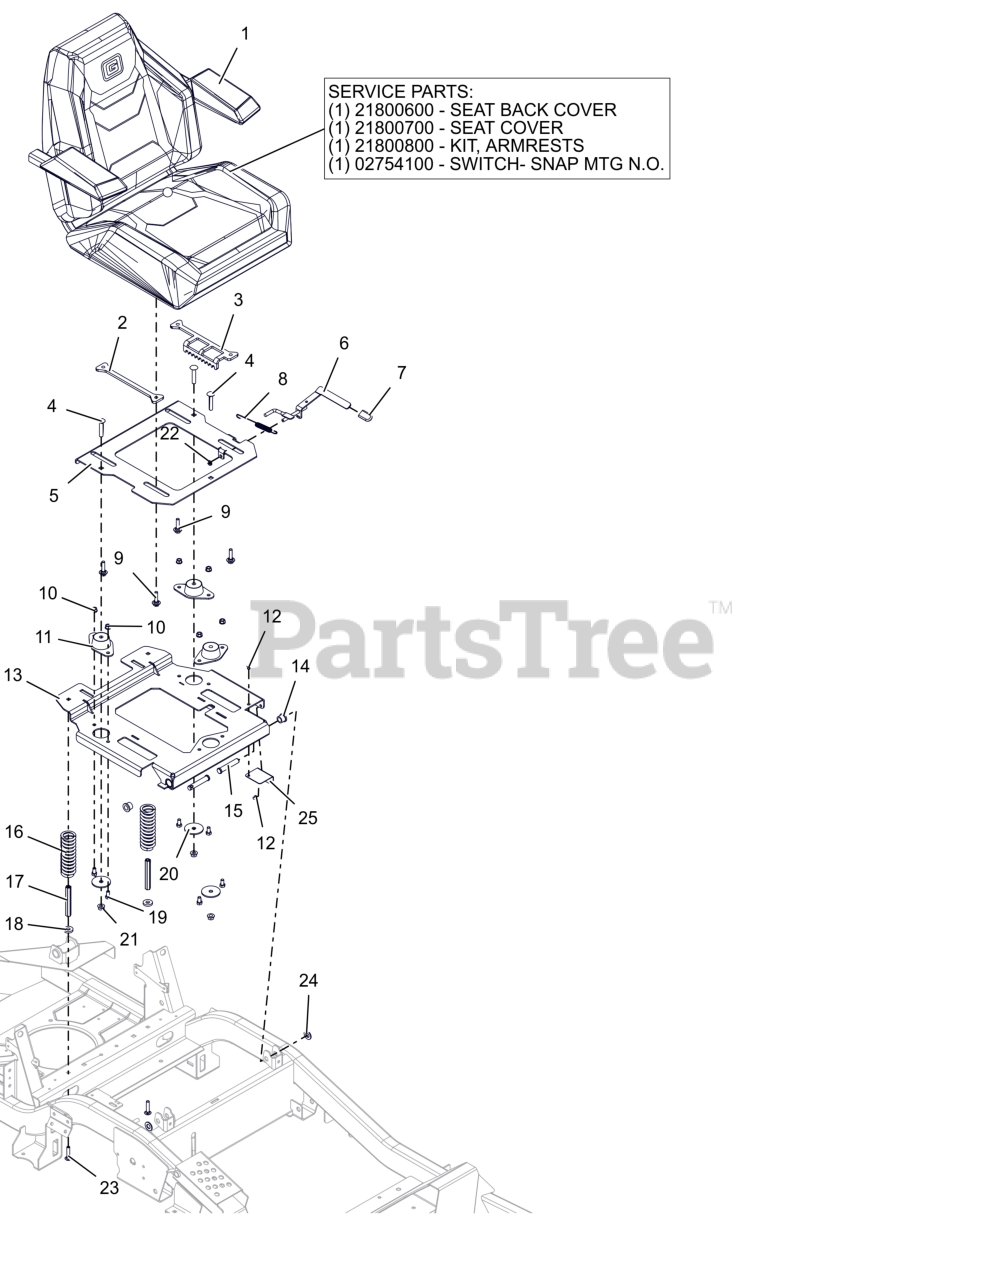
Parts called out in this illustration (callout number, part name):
1	SEAT- ZTXL MY23 (WOOD)
1	KIT- ZTXL CUSTOM BACK COVER
1	KIT- ZTXL CUSTOM SEAT COVER
1	KIT- ARMRESTS (CUSTOM PAD)
1	SWITCH- SNAP MTG N.O.
2	PLATE, ADJ SEAT SLIDE (BLACK)
3	PLATE, SEAT ADJ (BLACK)
4	BLT,RHSSN.375-16X2.00 G5 ZCC
5	PLATE- SEAT MTG 3PT (ISO KIT)
6	WLDMT, SEAT SLIDE LEVER
7	GRIP, SEAT LEVER, GREY
8	SG-TENS .06X.482X5.35
9	BLT, SHLDR .31-18 X .175
10	NUT,LK-CTR-FLG .31-18 GF ZCC
11	MOUNT- FAIL-SAFE COMPRESSION
12	RIVET, .1875 AL/AL .126-.250
13	WLDMT- ISO MTG PLATE 3PT
14	BSHG, FLG .516X.750X.625X.937
15	PIN, SLIC-.500X42.70X2.31 -ZC
16	SPRING, COMPRESSION SEAT 224LB
17	NUT, COUPLING 5/16X18 X 3.75
18	WSHR, FLT .406X1.00X.188 ZCC
19	BLT, HEX .31-18X.625 G5 ZCC
20	WSHR-FL-STL 0.406X2X0.125 ZCC
21	NUT-LK-CTR-FLG .375-16 GF ZCC
22	NUT-PUSH .312
23	BLT,RHSN .31-18X1.50 G5 ZCC
24	WSHR-FL-NYL .518X1.000X.080
25	GUARD, SEAT FAN (SH)(BLACK)
